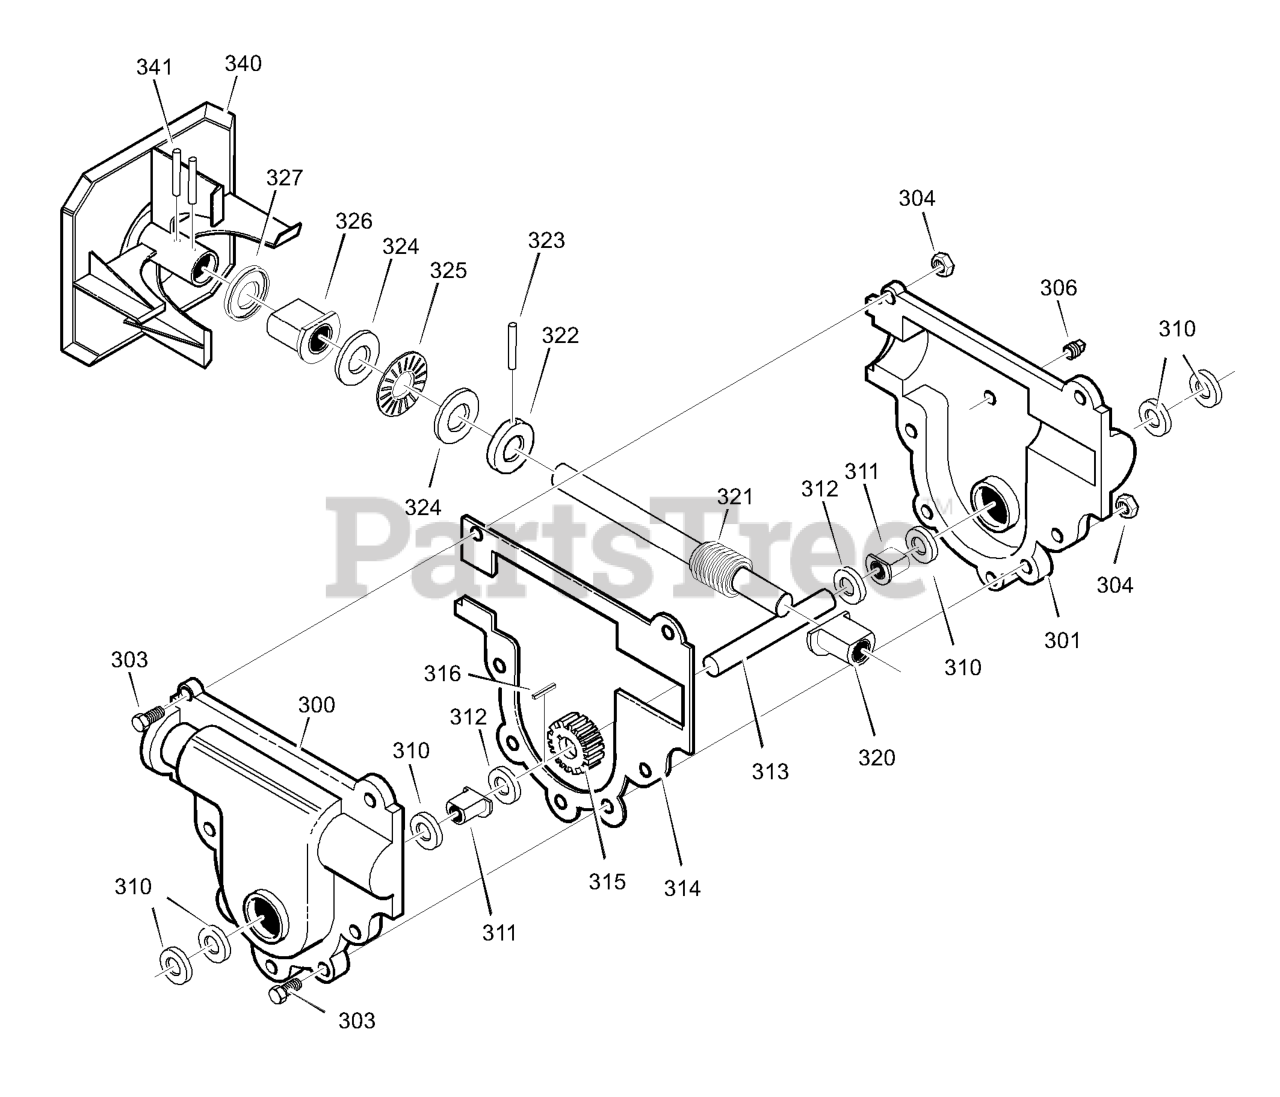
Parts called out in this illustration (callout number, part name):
300	CASE, GEAR, RH
301	CASE, GEAR, LH
303	SCREW,1/4-20X.75
304	NUT,1/4-20
306	SCREW, 3/8-16 x 0.50
310	SEAL, OIL
311	BEARING, FL
312	WASHER, FLAT
313	SHAFT, AUGER OUTPUT
314	GASKET, GEAR BOX
315	GEAR, WORM
316	KEY, WOODRUFF #61
320	BRNG, FL
321	SHAFT, AUGER INPUT (IMPELLER)
322	COLLAR, THRUST
323	PIN, SPRING
324	WASHER, FLAT
325	BRNG, ROLL
326	BRNG, FL
327	SEAL, OIL
341	PIN, SPRING
